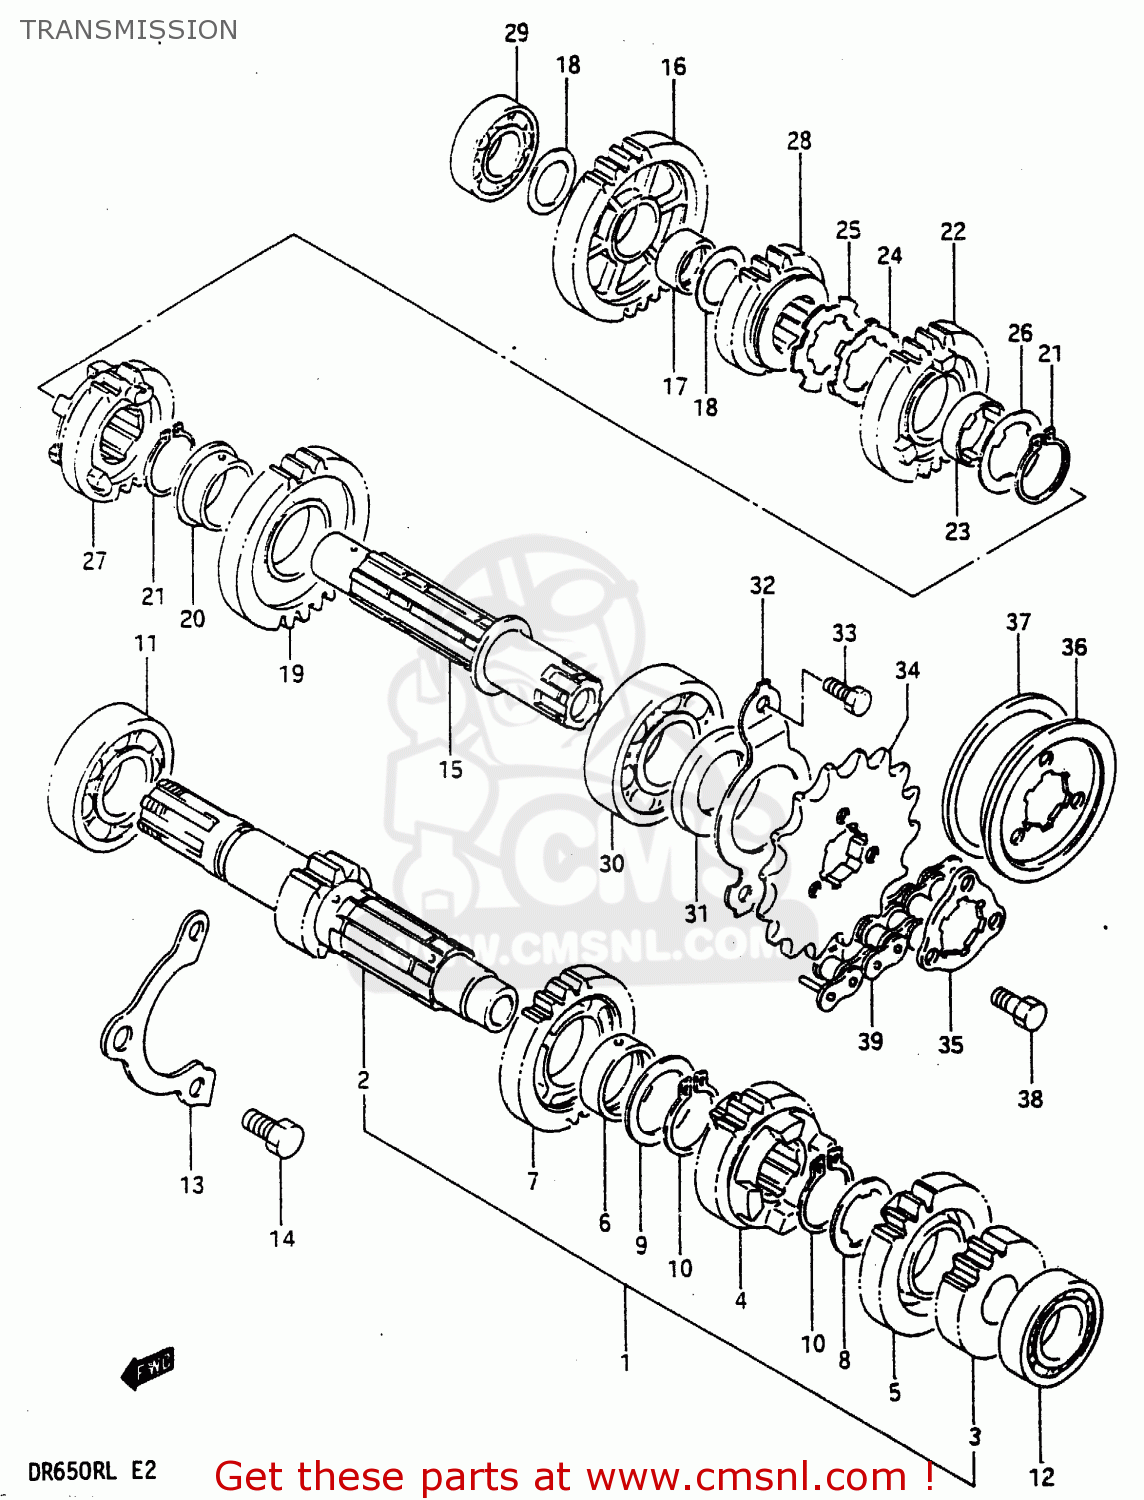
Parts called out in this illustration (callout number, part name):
1	SHAFT,COUNTER
2	SHAFT,COUNTER
3	GEAR,SECOND DRIVE
4	GEAR,THIRD DRIVE
5	GEAR,FOURTH DRIVE
6	BUSHING 25X29X10
7	GEAR,5TH DRIVE
8	WASHER,LOCK
9	WASHER
10	RING,SNAP
11	BEARING
12	BEARING
13	RETAINER,CNTR SHAFT BEARING
14	BOLT, 8X1.25X1
15	SHAFT,DRIVE
16	GEAR,1ST DRIVEN
17	BUSH(20X24X13)
18	WASHER
19	GEAR,2ND DRIVEN
20	BUSH
21	RING,SNAP
22	GEAR,THIRD DRIVEN
23	BUSHING
24	WASHER
25	WASHER,LOCK
26	WASHER,LOCK
27	GEAR,FOURTH DRIVEN
28	GEAR,FIFTH DRIVEN
29	BEARING(20X42X12)
30	BEARING(25X62X17)
31	SEAL,OIL(25X45X5)
32	RETAINER,DRIVESHAFT O
33	BOLT
34	SPROCKET,ENGINE(NT:16)
35	PLATE,ENGINE SPROCKET
36	PLATE,ENGINE SPROCKET
37	DAMPER,ENGIN SPROCKET
38	BOLT(6X13)
39	CHAIN ASSEMBLY,DRIVE
